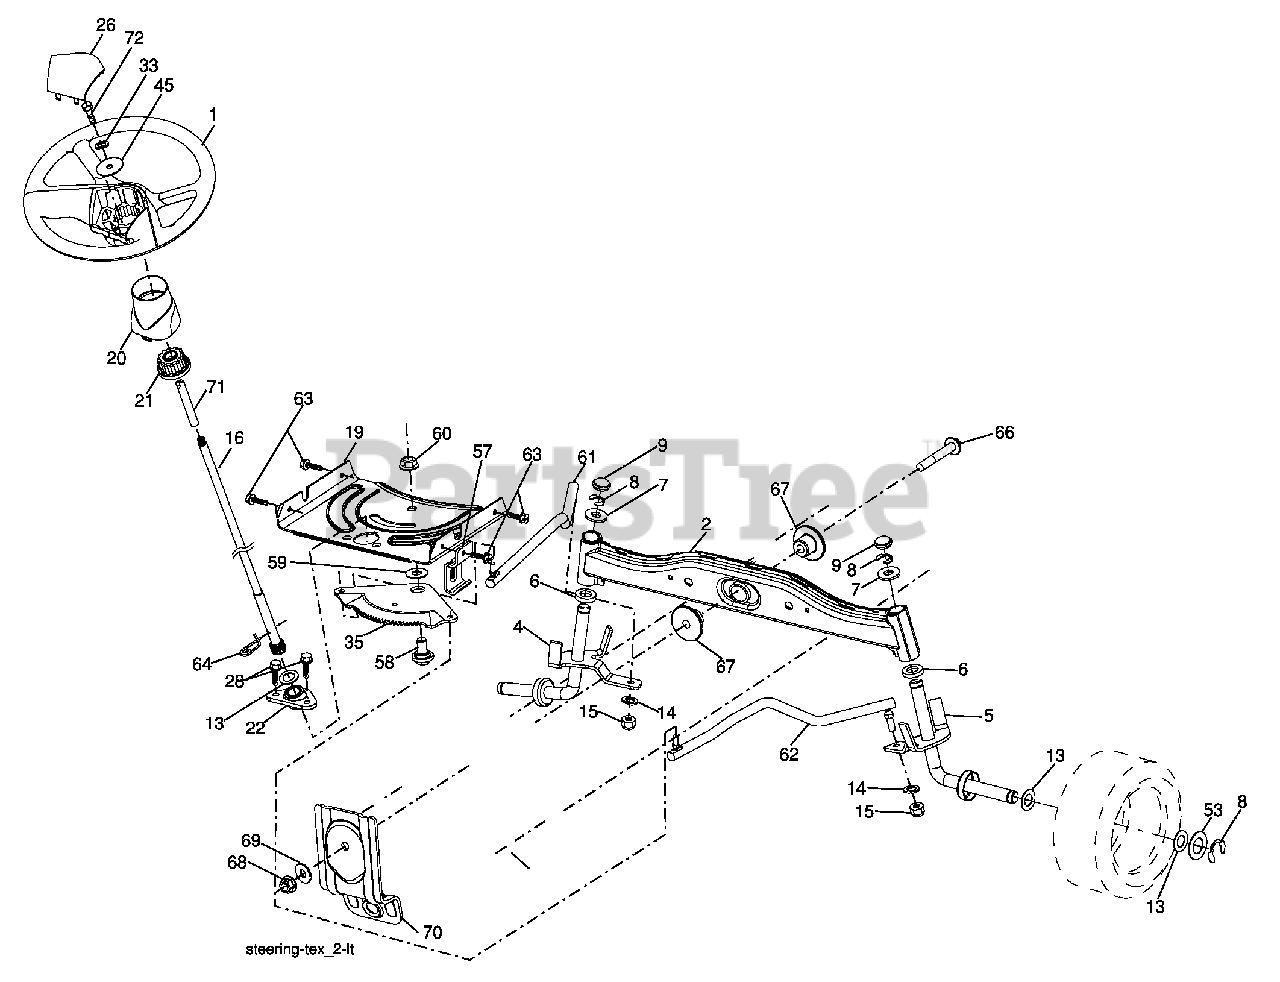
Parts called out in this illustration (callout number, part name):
1	Wheel, Steering
2	Axle Asm., Front
4	Spindle Asm., LH
5	Spindle Asm., RH
6	Bearing, Race Thrust Harden
7	Washer 25/32 x 1-5/8 x 16 Ga.
8	Ring, Klip #T5304-75
9	Cap, Spindle
13	Washer 25/32 x 1-1/4 x 16 Ga.
14	Washer, Lock Hvy Hlcl Spr 3/8
15	Nut, Crown Lock 3/8-24 unf
16	Shaft Steering
19	Plate Steering
20	Boot, Steering
21	Adapter, Wheel Steering
22	Bushing, Strg. Blk
26	Insert, Wheel Steering
28	Screw 3/8-16 x 3/4
33	Washer Lock 5/16
35	Gear, Sector Plate
45	Washer 11/32 ID x 2-3/8 x 12 Ga.
53	Washer Hardened .793 x 1.637 x .060
57	Bracket Upstop
58	Bolt Shoulder Sector Pivot CFM
59	Washer Thrust Sector Steering
60	Nut Flange Lock 5/8-11
61	Draglink LH
62	Draglink, RH
63	Screw 5/16-18 x 3/4
64	Retainer Clip Spring Steering
66	Bolt Hex Fghd 7/16-14 x 3 Serr
67	Bushing PM Front Axle
68	Nut Lock Flange 7/16-14 Gr. 5
69	Washer 1.5 x .505 x .118
70	Bracket Deck Susp. Front
71	Shaft Exten Strg.
72	Bolt Fin Hex 5/16-18 UNC x 4.5 G5
